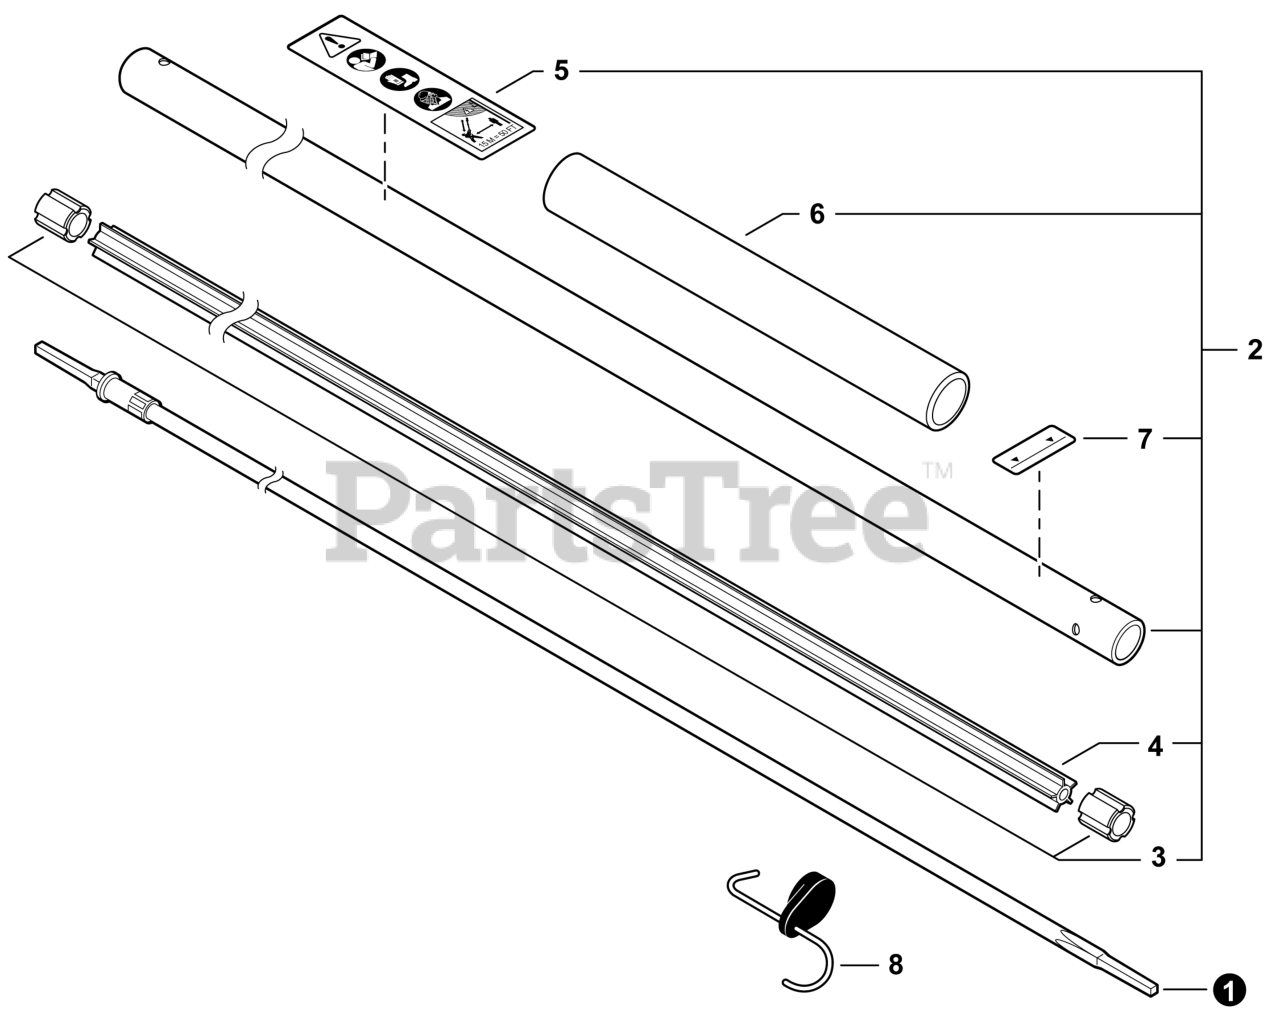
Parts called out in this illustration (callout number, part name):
1	DRIVESHAFT - FLEXIBLE
2	MAIN PIPE ASSY
4	LINER - FLEXIBLE
5	LABEL - CAUTION
6	GRIP, HANDLE
7	LABEL - ALIGNMENT
8	HANGER, ATTACHMENT
